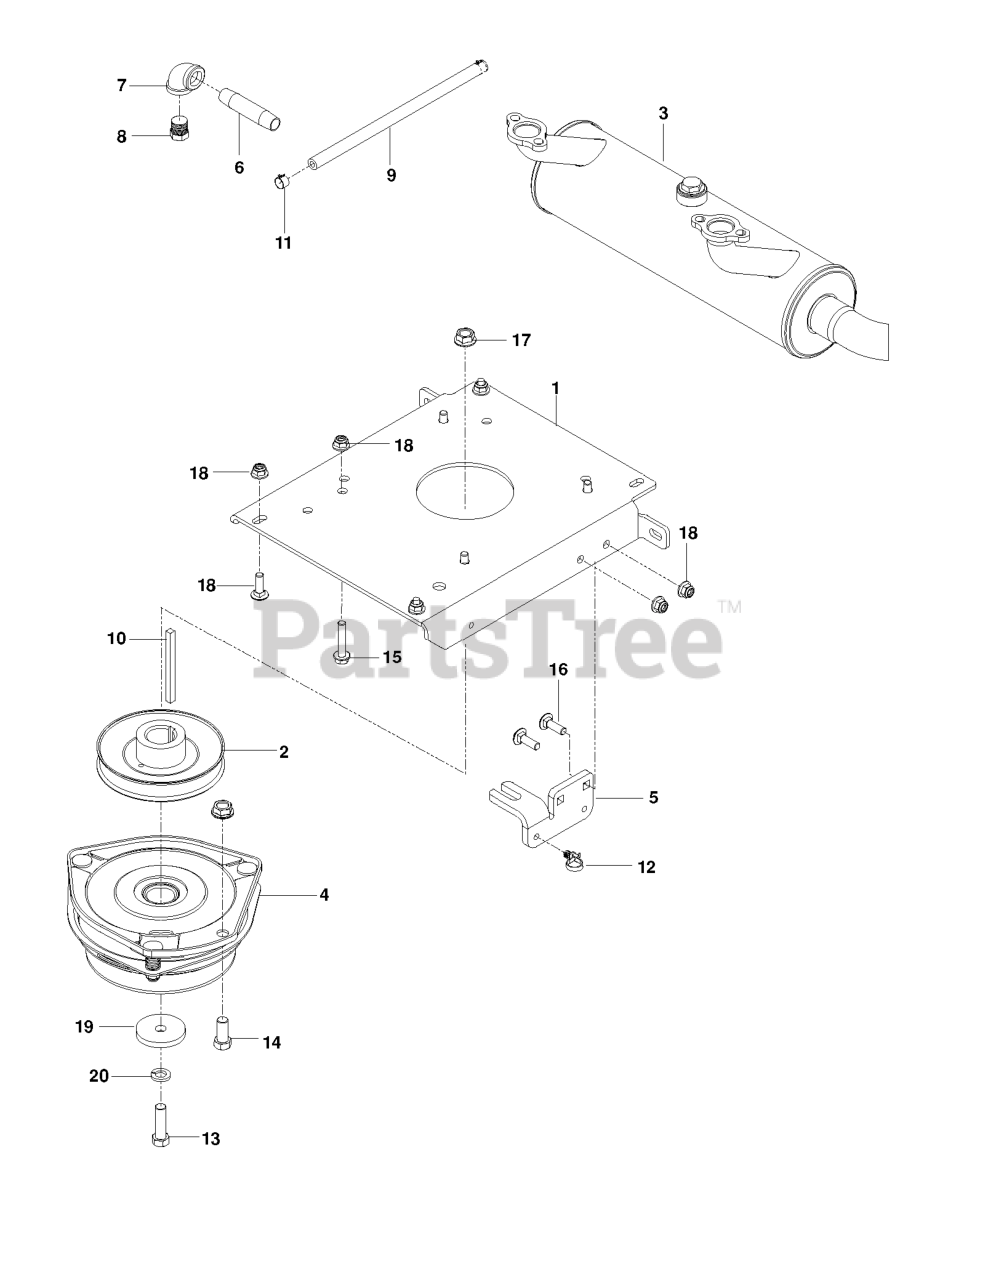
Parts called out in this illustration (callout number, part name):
1	PLATE.ENGINE.BLACK
2	PULLEY, ENGINE
3	MUFFLER.KOH.EFI.W/O2.SENSOR
4	CLUTCH, GT3.5
5	STOP, CLUTCH, OGURA
6	PIPE NIPPLE 3/8 X 3
7	90 DEG.ELBOW 3/8NPT
8	PLUG, DRAIN 3/8 NPTF
9	FUEL LINE 5"
10	KEY, 1/4 SQ X 3.5
11	HOSE CLAMP
12	TIE WRAP, 8-3/8", W/CLIP
13	HCS 7/16F X 1 1/2
14	HCS 7/16-14 X 1 GR 5 ZD
15	HHFS 5/16-18 X 1.5 GD 5
16	RHSNB 5/16C X 1
17	NUT 7/16C WHIZ
18	5/16-18 NYLOC FLANGE NUT
19	BLADE WASHER
20	WASHER 7/16 LOCK
